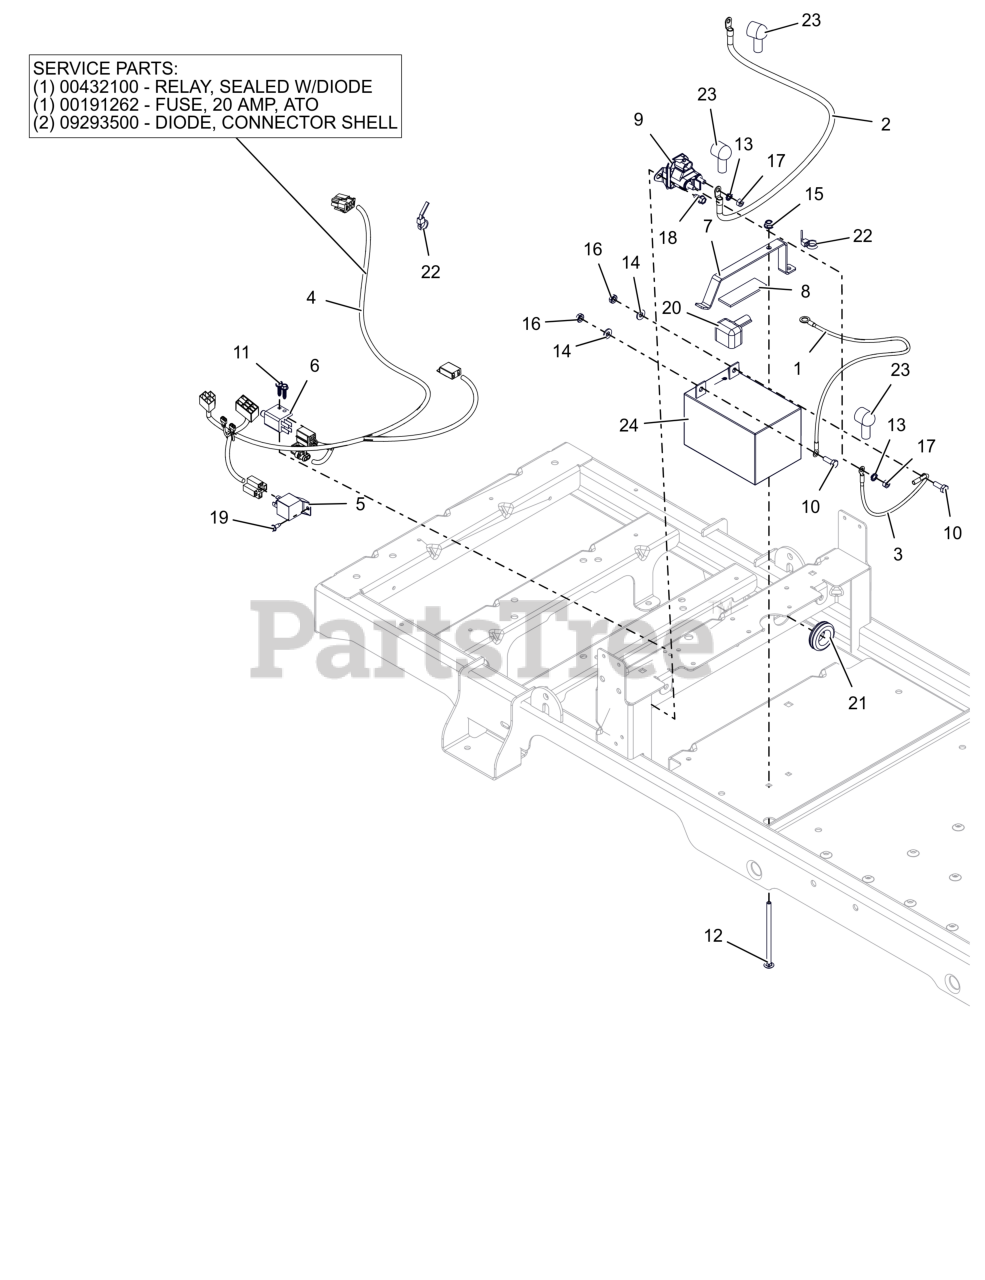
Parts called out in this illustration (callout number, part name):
1	CABLE, NEGATIVE 26" 6 GA.
2	CABLE,POS W/(2)1/4 RING 21.5LG
3	CABLE,POS W/2 1/4 RING 15.0 LG
4	HARNESS, ZOOM / ZT WIRE
4	RELAY,SEALED W/DIODE
4	FUSE, 20 AMP BLADE S/O
4	DIODE, CONNECTOR SHELL
5	RELAY,SEALED W/DIODE
6	SWITCH- DOUBLE POLE N.O./N.O.
7	HOLDDOWN, BATTERY, U1&190CCA
8	PAD,RBR 1.0"X3.0" W/ADHESIVE
9	SOLENOID, STARTER (SEALED)
10	BLT, HEX .25-20X.75 G5 ZCC
11	SCR, PLASTITE #12X.75 ZCC
12	BLT, RHSN .25-20X4.50 G5 ZCC
13	WSHR,LK-EXT.262X.502X.026 ZCC
14	WSHR,FLT .281X.625X.065 ZCC
15	NUT,NYL-FLG .25-20 GF ZCC
16	NUT-KEPS .250-20 ZCC
17	NUT-STD M6-1.0 ZCC
18	SCR-TAP .25-20X.50 HWH ZCC
19	@SCR-TAP 10-24X.50 HWH TR YWZC
20	INSULATOR
21	GROMMET 1.0ID X 1.38 OD
22	CABLE TIE LG 5-1/2
23	BOOT, EYELET TERMINAL
24	BATTERY, 12V 12AH -190CCA
